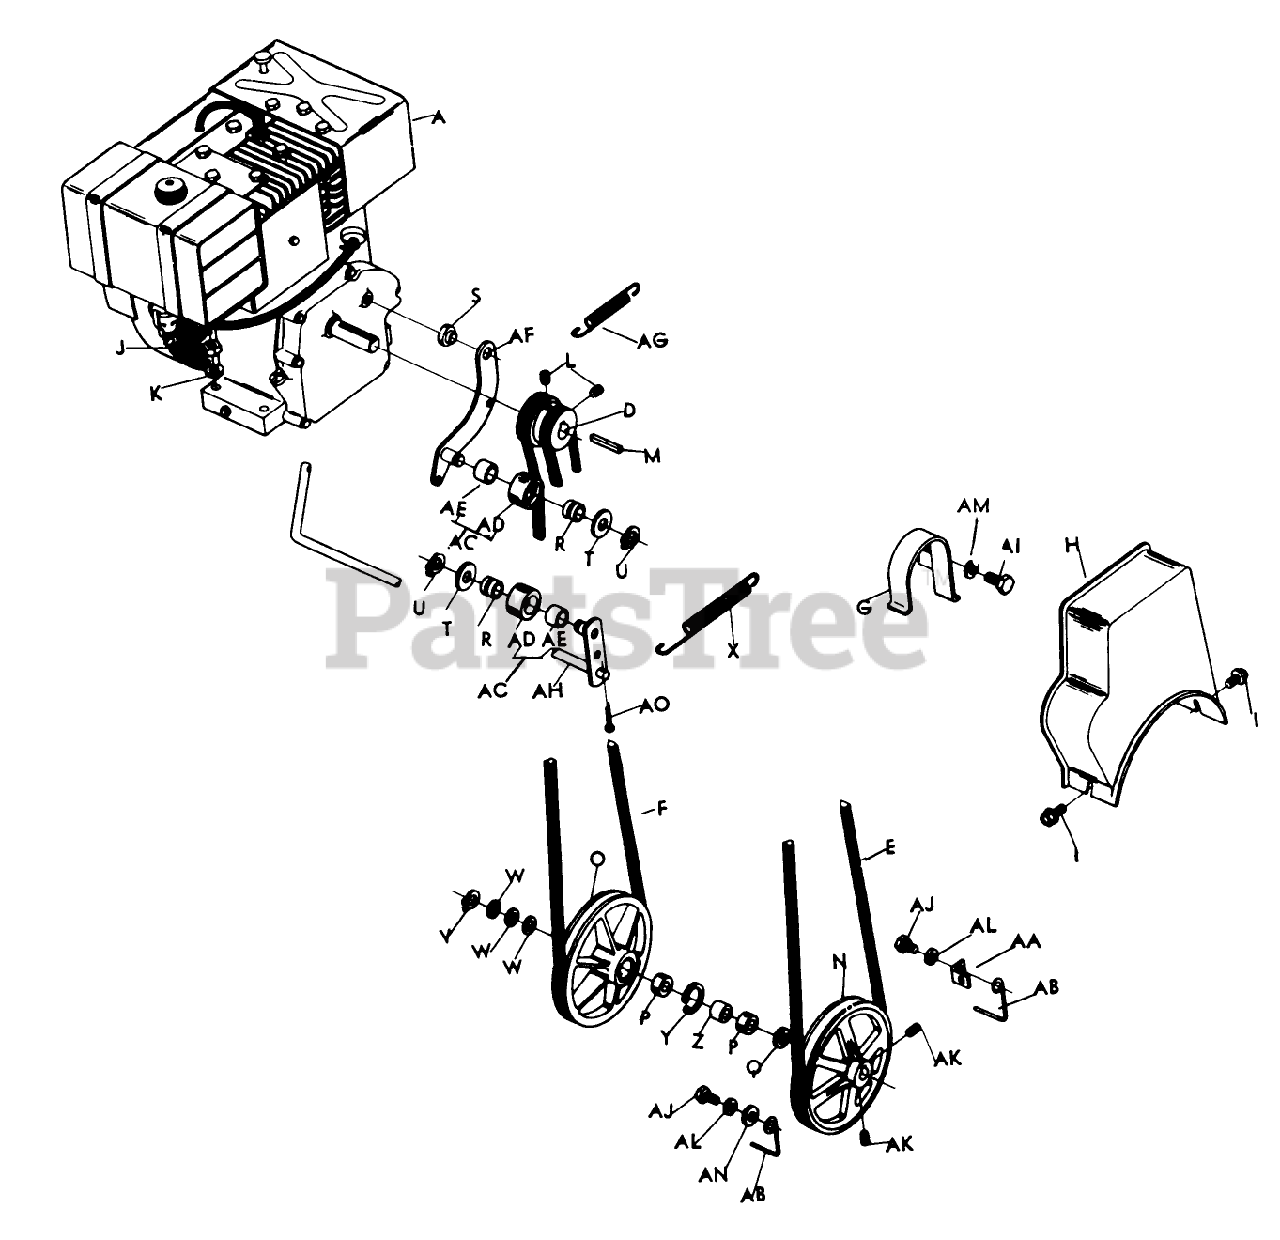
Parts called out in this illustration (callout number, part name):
A	Engine-5 H.P.-BS Model 130202-0237-02
J	5/16-18 Hex Nut-Pl.
K	5/16 Lockwasher-Pl.
L	5/16-18 x 5/16 Setscrew
AI	1/2-20 x 1 1/4 Hex Hd. Capscrew-Pl.
AJ	1/4-20 x 3/4 Hex Hd. Capscrew-Pl.
AK	3/8-16 x 3/4 Sq. Hd. Setscrew-H.T. Pl.
AL	1/4 Lockwasher-Pl.
AM	1/2 Lockwasher-Pl.
AN	1/4 Flat Washer-Pl.
AO	1/8 x 3/4 Cotter Pin-Pl.
